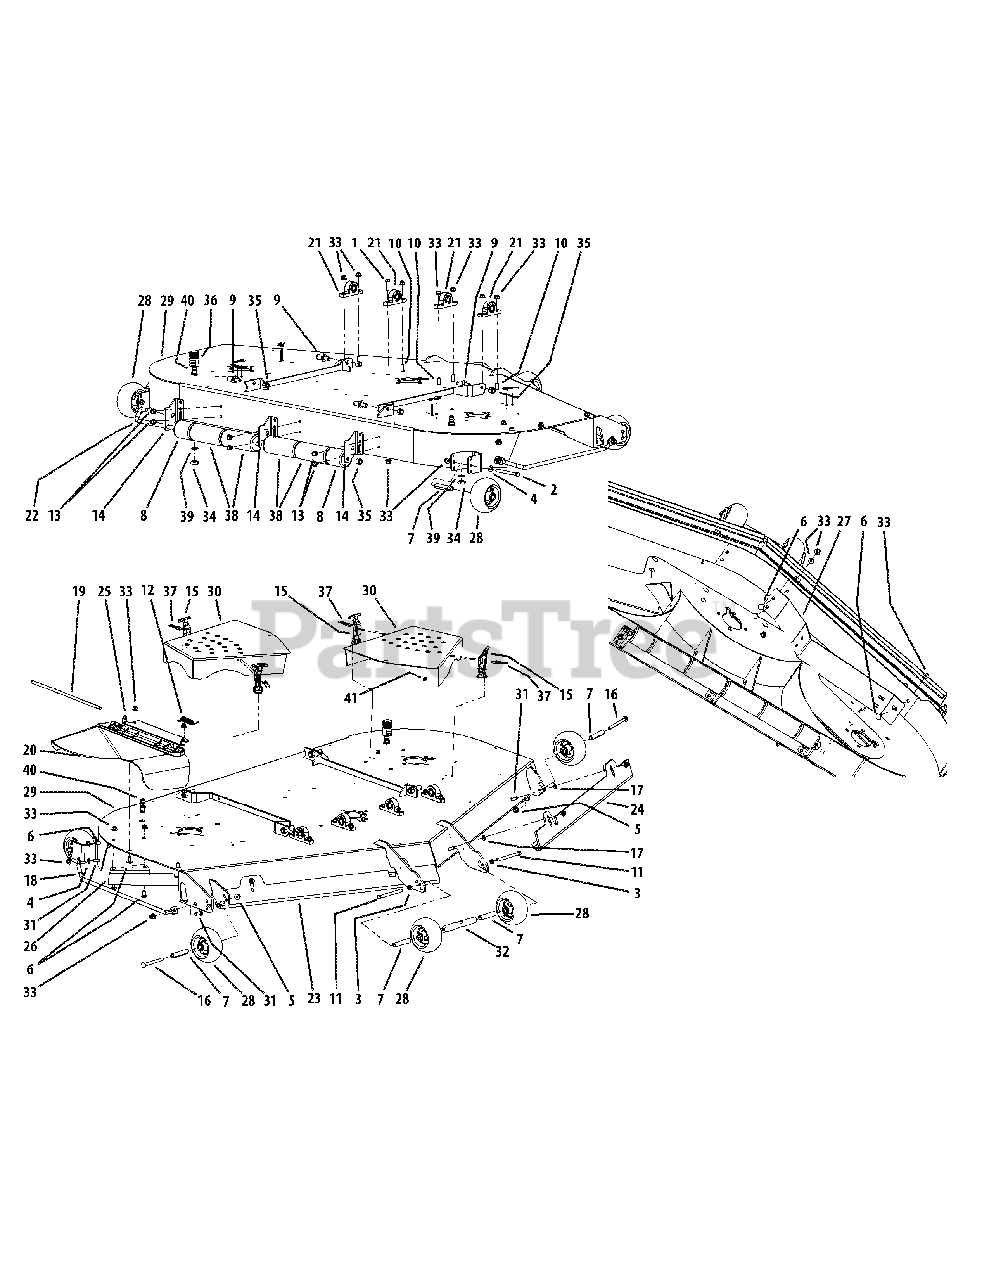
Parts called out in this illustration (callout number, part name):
1	Hex Cap Screw, 3/8-16, 1.25
2	Hex Cap Screw, 3/8-16, 4.00
3	Lock Washer, 3/8
4	Flat Washer, 3/8
5	Flange Lock Hex Nut, 3/8-16
6	Carriage Bolt, 3/8-16 x .75 Lg.
7	Wheel Spacer
8	Grass Catcher Roller
9	Pin, 5/8 Dia. x 1.2 Lg.
10	Carriage Screw, 3/8-16 x 1.25
11	Hex Cap Screw, 3/8-16 x 4.50
12	Torsion Spring, 0.4ID x 2.16Lg
13	Hex Index Washer Screw, 3/8-16, .5
14	Deck Roller Mount Bracket
15	T-Handle Latch Draw
16	Carriage Bolt, 3/8-16 x 4.00
17	Push Retainer
18	Finger Guard
19	Pin, .375 x 14.06
20	Chute Deflector
21	Pillow Block, Steel
22	J-Hook w/ Threaded Roller
23	Right Hand Front Adjustment Skirt
24	Left Hand Front Adjustment Skirt
25	Chute Deflector Bracket
27	Baffle, 72" Adjustment
28	Complete Wheel, 5.00 Dia.
29	72" Deck Assembly
30	Deck Belt Cover
31	Carriage Bolt, 3/8-16 x 1
32	Ball Wheel Mounting Shaft
33	Flange Lock Hex Nut, 3/8-16
34	Hex Nut, M16-1.5
35	Lock Nut, Nylon Insert, 1/2-13
36	Water Nozzle Adaptor
37	Phillips Head Screw, #10-32 x 1/2
38	Front Roller
39	Lock Washer, 17 x 23.8 x 1.95
40	Deck Water Nozzle
41	Lock Nut, Nylon Insert, #10-32
